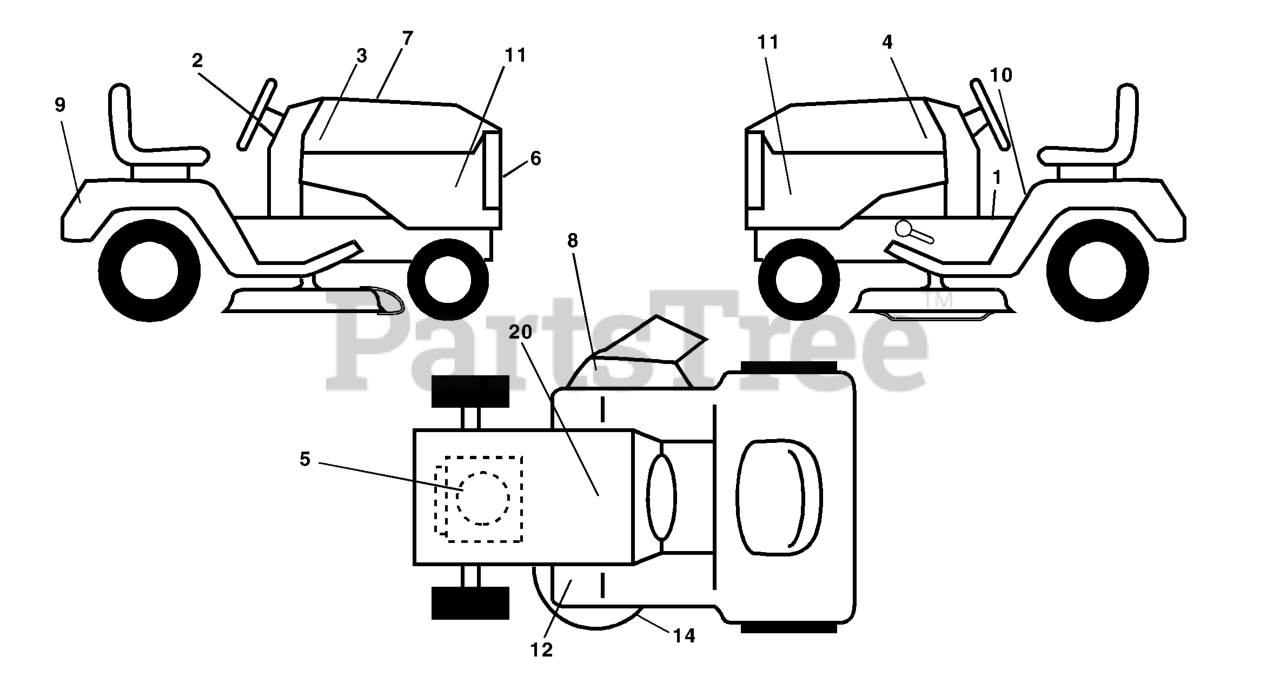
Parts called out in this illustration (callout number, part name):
2	DECAL.WHEEL.STEERING.HUSQ.PERM
3	DECAL HOOD RH
4	DECAL HOOD LH
5	DECAL ENGINE
6	DECAL.GRILLE.HUSQ
7	DECAL, 'REPLACEMENT PARTS'
8	DECAL.WARN.KEEP.HAND.AWAY
9	DECAL, FENDER
10	DECAL FENDER DANGER
11	DECAL HOOD SIDES
12	DECAL CLUTCH/BRAKE
14	DECAL V-BELT SCHEMATIC
20	DECAL BTRY SYMBOLS
